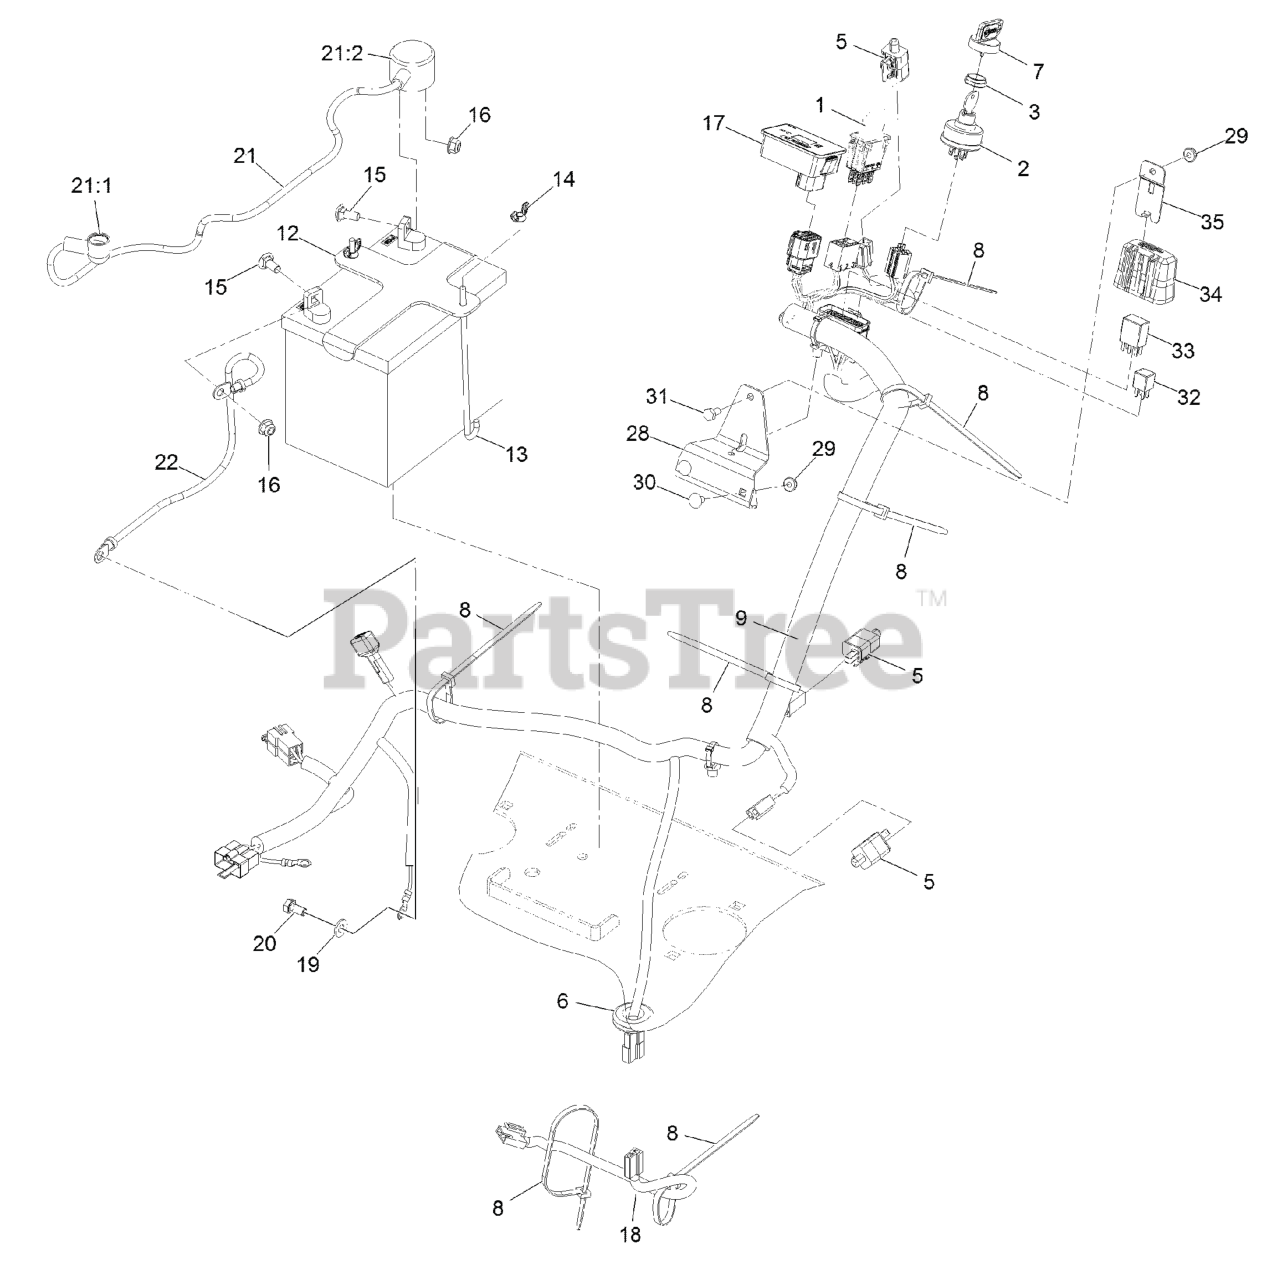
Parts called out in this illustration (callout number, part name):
1	SWITCH-PTO
2:1	WASHER-LOCK
3	NUT-SWITCH, IGNITION
6	GROMMET
7	KEY-IGNITION
8	TIE-PLASTIC
9	HARNESS-MAIN TTX KAWASAKI
9:1	FUSE-BLADE TYPE, 20 AMP
13	BOLT-HOLDDOWN
14	WINGNUT
15	BOLT-CARR
16	NUT-HF, NI
17	MODULE-HOUR METER
18	HARNESS-CLUTCH PIGTAIL
19	WASHER-PLAIN
20	SCREW-HH
21	POSITIVE BATTERY CABLE AS
21:1	INSULATOR-SOLENOID
21:2	INSULATOR-BATTERY
24	NUT-LOCK, NI
25	TIE-PLASTIC
